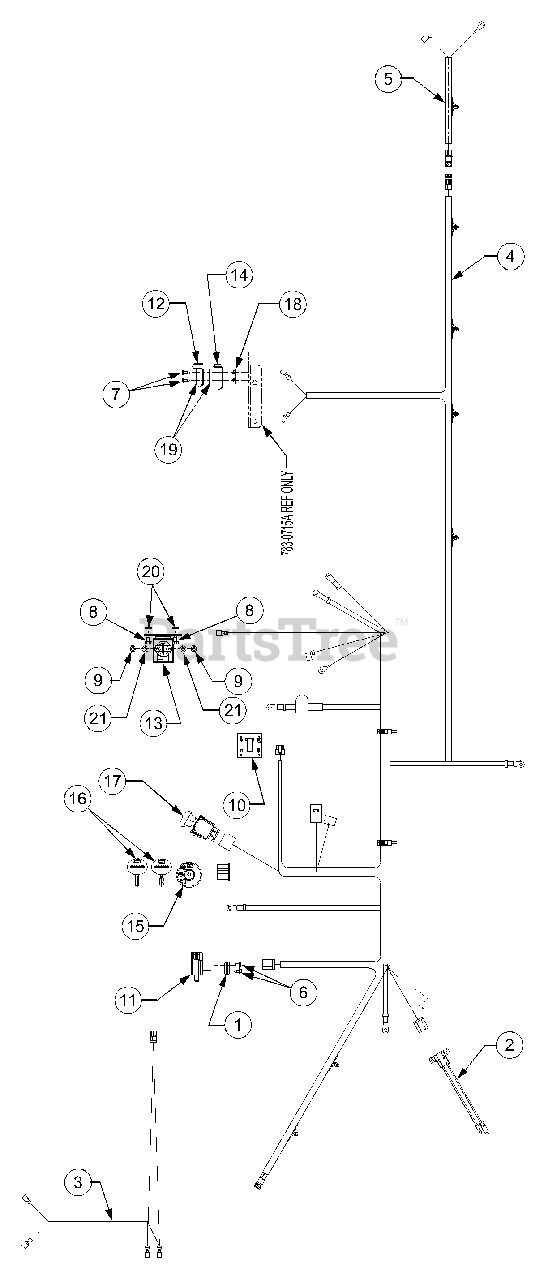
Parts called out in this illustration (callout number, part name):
1	Plate, Switch
2	Harness Assembly, Kawasaki
3	Harness Assembly, Headlight
4	Harness Assembly
5	Harness Assembly, Safety, Reverse
6	Screw, Hx. Wash. Hd. Tapp, 10-16 x .5
7	Screw, Hx. Wash. Hd. Tapp, 8-18 x .5
8	Screw, Hx. Wash. Hd. Tapp, 1/4-20, 0.5
9	Nut, Hex, 1/4-20, Gr5
10	Indicator/ Meter Hour
11	Switch, Interlock
12	Switch, Outer Seat Spring
13	Solenoid, Starter, 12V
14	Switch, Inner Seat Spring
15	Switch, Key, 4-Position
16	Key, Switch, Plastic
17	Switch, Electric PTO, Yellow Knob
18	Plate, Insulator Boss
19	Plate, Insulator
20	Washer, Lock, Ext 1/4
21	Washer, Lock, 1/4
